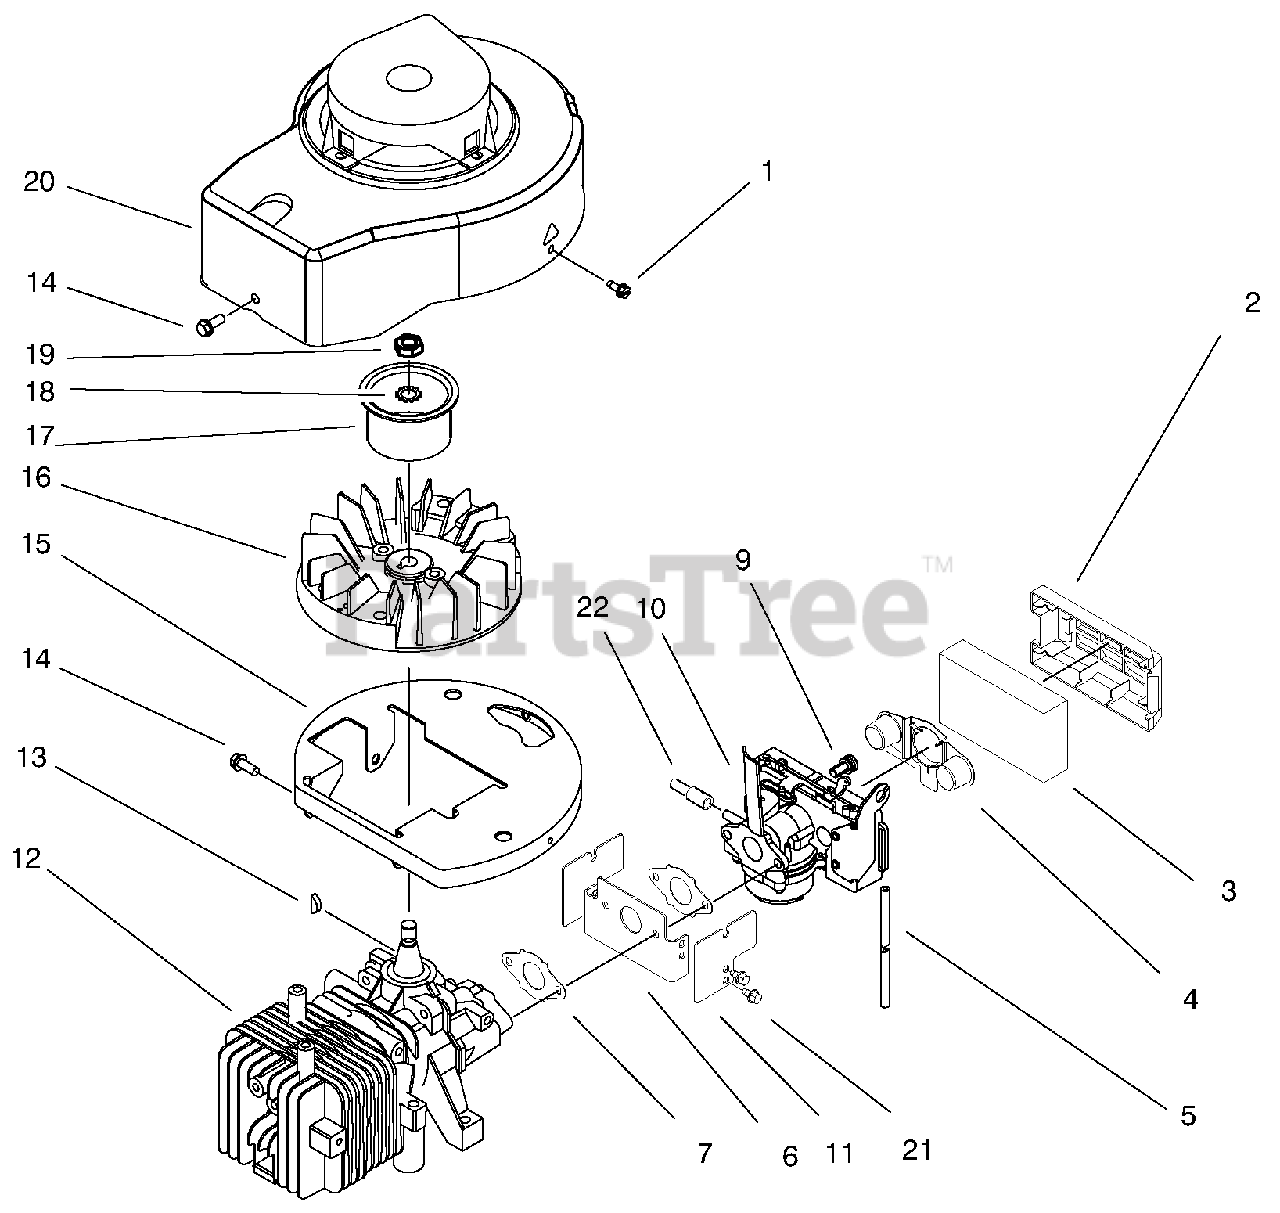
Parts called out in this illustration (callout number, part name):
2	Cover-Air Filter
3	Element-Air Filter
4	Shield-Fuel
5	Hose-Primer
6	Shield-Carburetor
7	Gasket-Carburetor
10	Carburetor Assembly
11	Shield-Governor
12	Short Block Assembly
14	Screw
15	Base-Shroud
16	Flywheel Assembly
17	Hub-Starter
18	Washer-Lock
20	Shroud
